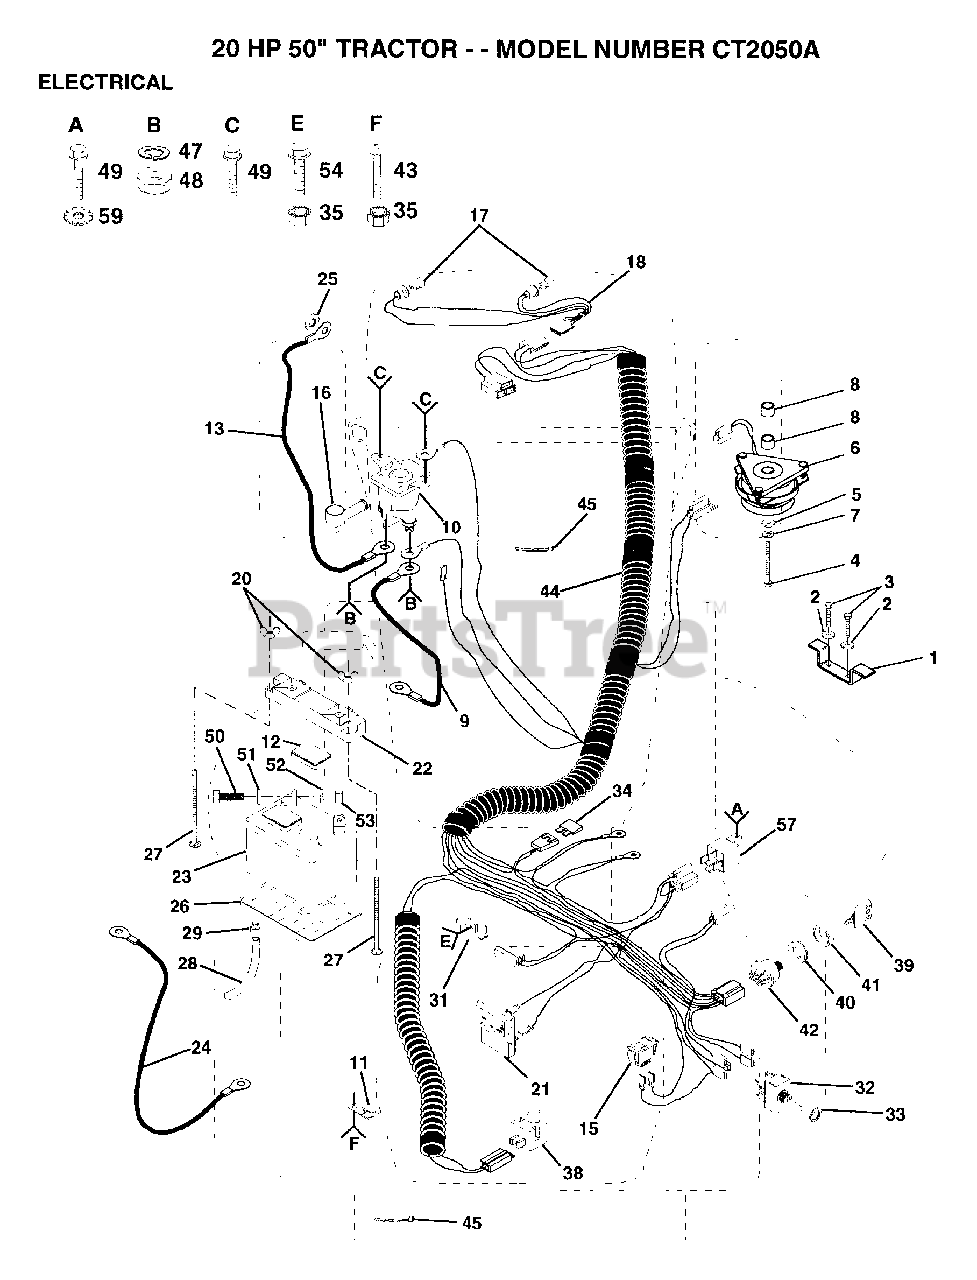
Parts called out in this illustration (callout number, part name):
2	LOCKWASHER
3	BOLT
5	WASHER
7	LOCKWASHER
8	SPACER-CLUTCH
9	CABLE-BATTERY T
12	"CAP,BATTERY "
13	"CABLE,STARTER T"
15	SWITCH LT
17	HEADLAMP BULB
18	"HARNESS,LIGHT SOC"
21	AMMETER
24	CABLE T
25	LOCKWASHER
26	"TRAY T, BATTERY"
27	BOLT
29	HOSE CLAMP T
31	SWITCH-INTER. GT
32	"SWITCH,PTO"
33	HEX NUT T
34	FUSE HYT
35	"NUT,KEPS"
38	SWITCH SEAT
39	KEY
40	NUT IGNITION
44	HARNESS.IGN
45	WIRE TIE
48	NUT
50	BOLT LT
51	WASHER
52	LOCKWASHER
54	SCREW
57	RELAY ASSY T
59	LOCKWASHER
79	SCREW ST
